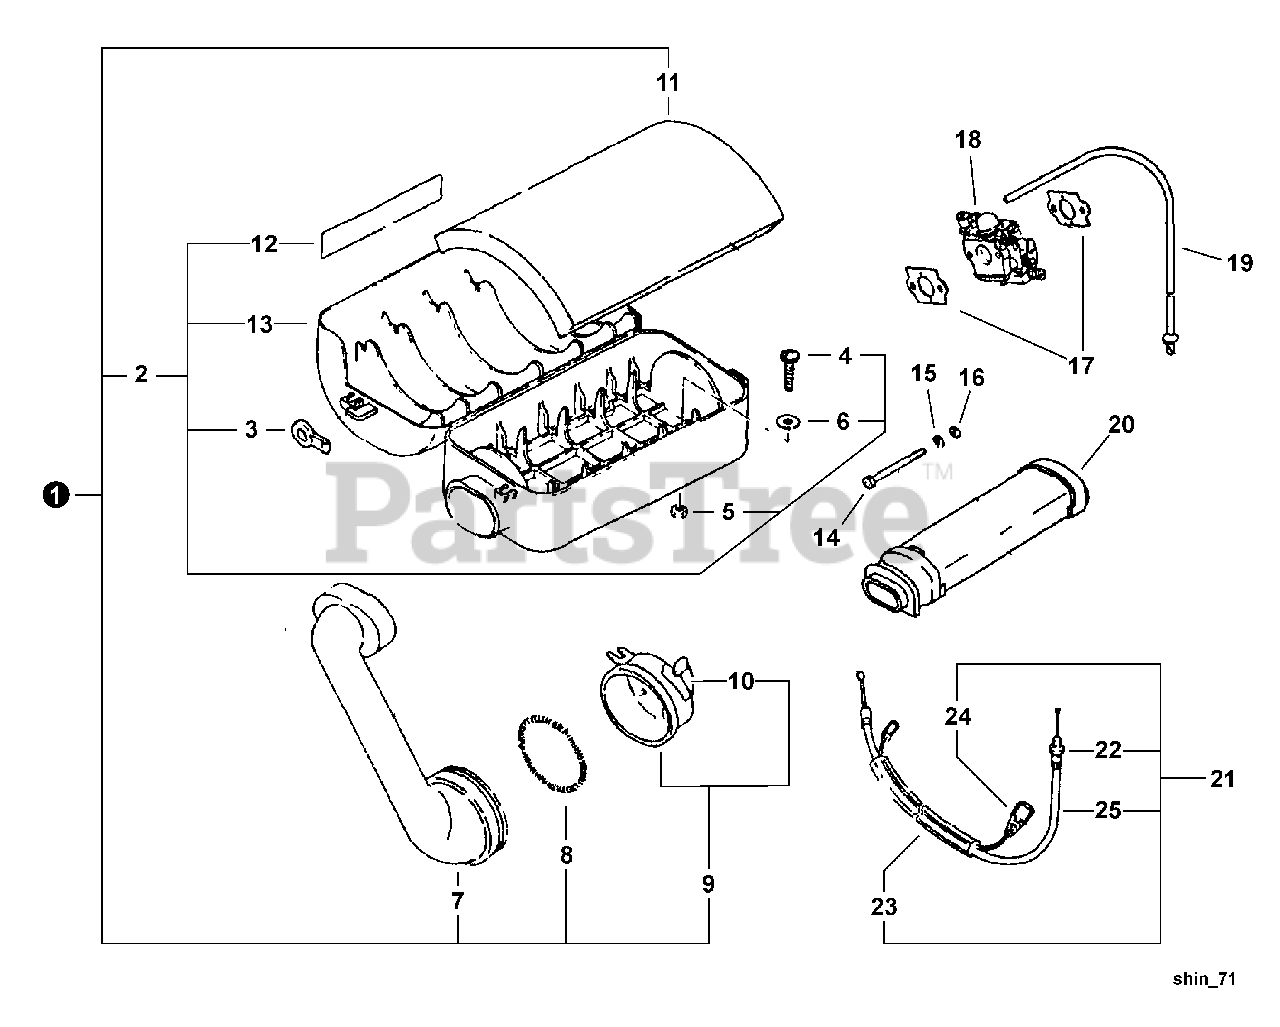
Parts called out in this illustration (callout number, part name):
1	AIR CLEANER ASSY
2	AIR FILTER COVER KIT
4	SCREW - 6X40
5	NUT - 6
6	WASHER
9	CASE, AIR FILTER
10	LABEL - CHOKE
11	FILTER, AIR
12	LABEL - CAUTION
13	CASE, AIR FILTER
14	SCREW - 5X55
15	LOCKWASHER - 5
16	WASHER - 5
17	GASKET, INTAKE
18	CARBURETOR
19	DRAIN PIPE ASSY
20	FILTER, AIR - HEAVY DUTY
21	CONTROL CABLE ASSY
22	NUT - 6
23	TUBE
24	LEAD - GROUND
25	CABLE, THROTTLE
